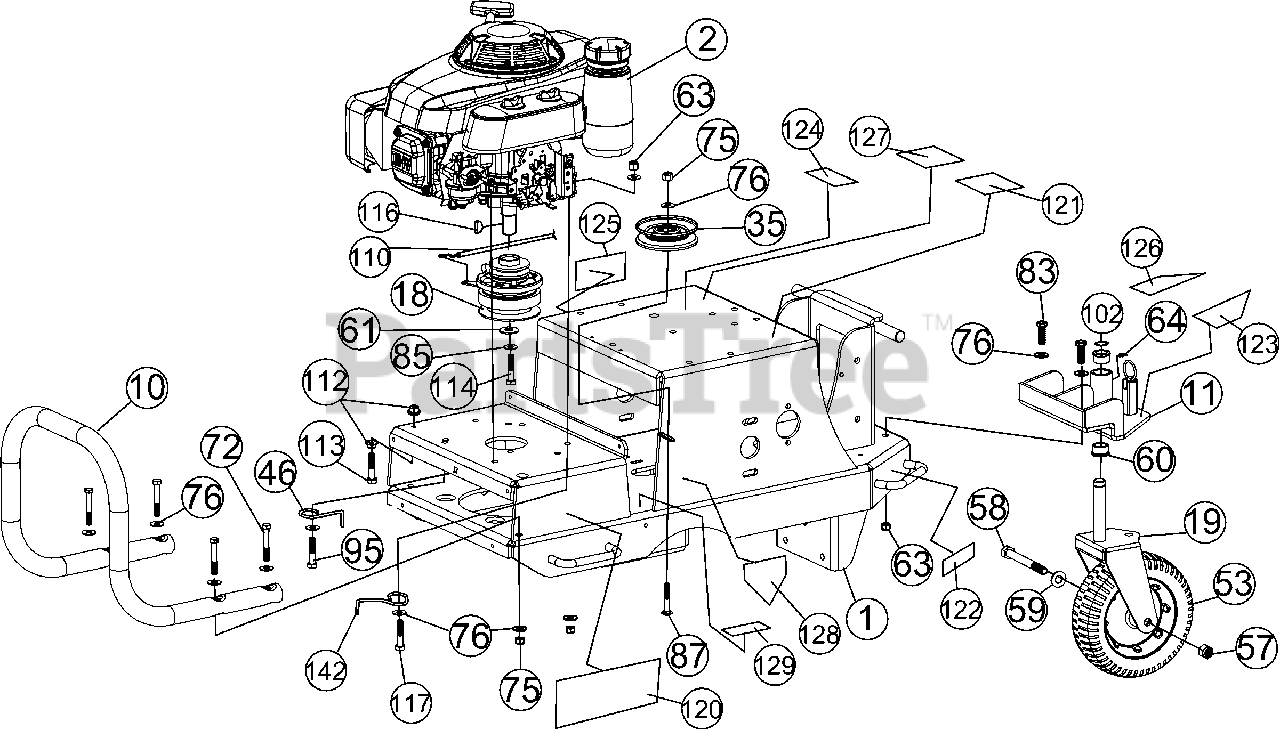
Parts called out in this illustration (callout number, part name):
1	FRAME WA SC
2	ENGINE GXV 160
10	TUBE BUMPER SC
11	CASTER MOUNT WA
18	CLUTCH SC
19	CASTER RIG WA
35	PULLEY IDLER 5L INSIDE 4"
46	BELT FINGER
53	WHEEL 8" X 3" HEAVY DUTY
57	NUT LOCK 1/2"-13 HEX
58	SCREWCAP 1/2"-13 X 4 3/4" HCS ZP
59	WASHER 1/2" SAE
60	BUSHING FLANGE 1" OD X 3/4" ID
61	WASHER 1.5" OD X .453 ID X .25 THK
63	NUT LOCK 3/8"-16
64	GREASE ZERK
72	SCREWCAP 5/16"-18 X 2 1/4 GR 5 HCS ZP
75	NUT LOCK 5/16"-18
76	WASHER 5/16" FLAT
83	SCREWCAP 3/8"-16 X 1 1/4" HC ZP
85	LOCK WASHER 3/8" S/T MED
87	CARRIAGE BOLT 3/8"-16 X 2" ZP
95	SCREWCAP 5/16"-18 X 1 3/4" GR. 5 HCS ZP
102	SNAP RING
110	CABLE SPEED CONTROL LEFT SERVICE
112	NUT WHIZ 1/4-20 WASH FACE
113	SCREWCAP 1/4"-20 X 1 1/2" HCS ZP
114	SCREWCAP 3/8"-24 X 1 1/2" GR. 8 40-45 FT-LBS (54-61 N.m)
116	KEY HI PRO 5/32 X 5/8"
117	SCREWCAP 5/16"-24 X 1 " GR. 8 ZP W/PATCH
120	LABEL BADGING SC
121	LABEL INSTRUCTION DRIVE
122	LABEL TIE DOWN
123	LABEL CASTER LOCK LEFT
124	LABEL DRIVE RELEASE SC
125	LABEL GREASE POINTS SC
126	LABEL CASTER LOCK RIGHT
127	LABEL INSTRUCTION DEPTH
128	LABEL DANGER
129	LABEL WARNING GUARDS
142	BELT FINGER TIGHT SIDE
